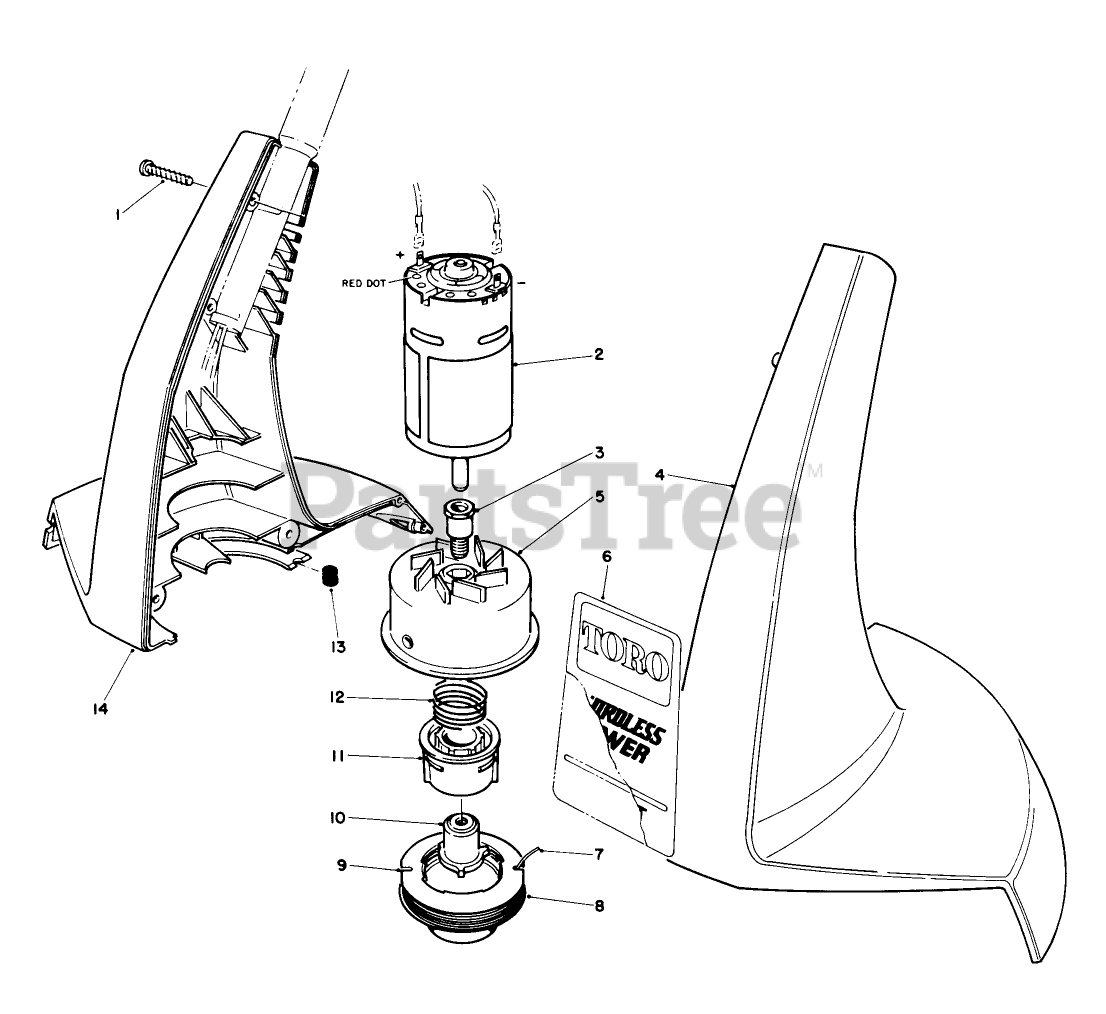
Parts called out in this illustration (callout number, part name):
1	Screw
2	Motor Assembly (Incl. Ref. #3)
3	Extension-Shaft
4	LH HOUSING, 12V TRIMMER
5	DRUM ASSEMBLY (8BLADE)
6	DECAL-TRIMMER
8	Pre-wound Spool (Incl. Ref. #7 & 9)
9	CAP-SPOOL
10	DRIVER
11	CORE - SPOOL
12	SPRING-COMPRESSION
13	GROMMET
14	RIGHT HAND HOUSING ASM
